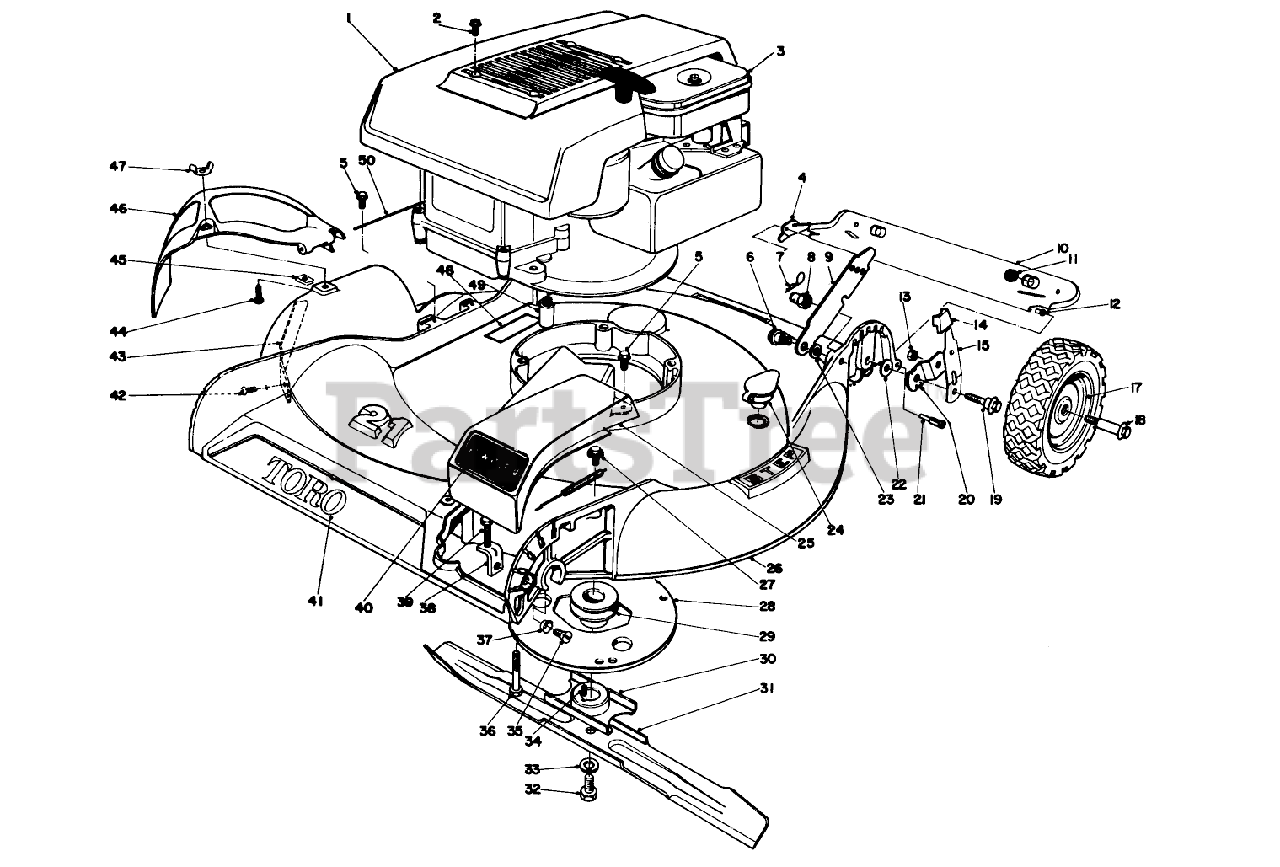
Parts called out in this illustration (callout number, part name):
3	Engine
5	SCREW
6	SCREW-SHOULDER
7	PIN-COTTER, HAIR
8	HANDLE PIVOT NUT
14	Arm Knob
19	PIVOT SCREW
20	PIVOT ARM PLATED
22	WASHER-PIVOT
23	SPACER
24	WASHOUT PLUG
25	Guard, Belt
26	Housing
27	SCREW-THD ROLL, HWH
33	WASHER-LOCK
35	SCREW-FH, S
36	3/8-16 X 2-3/4 CAPSCR
39	SCREW-HH
41	Decal Toro
42	SCREW-HWH
45	NUT-SPEED
47	NUT-WING SPECL
